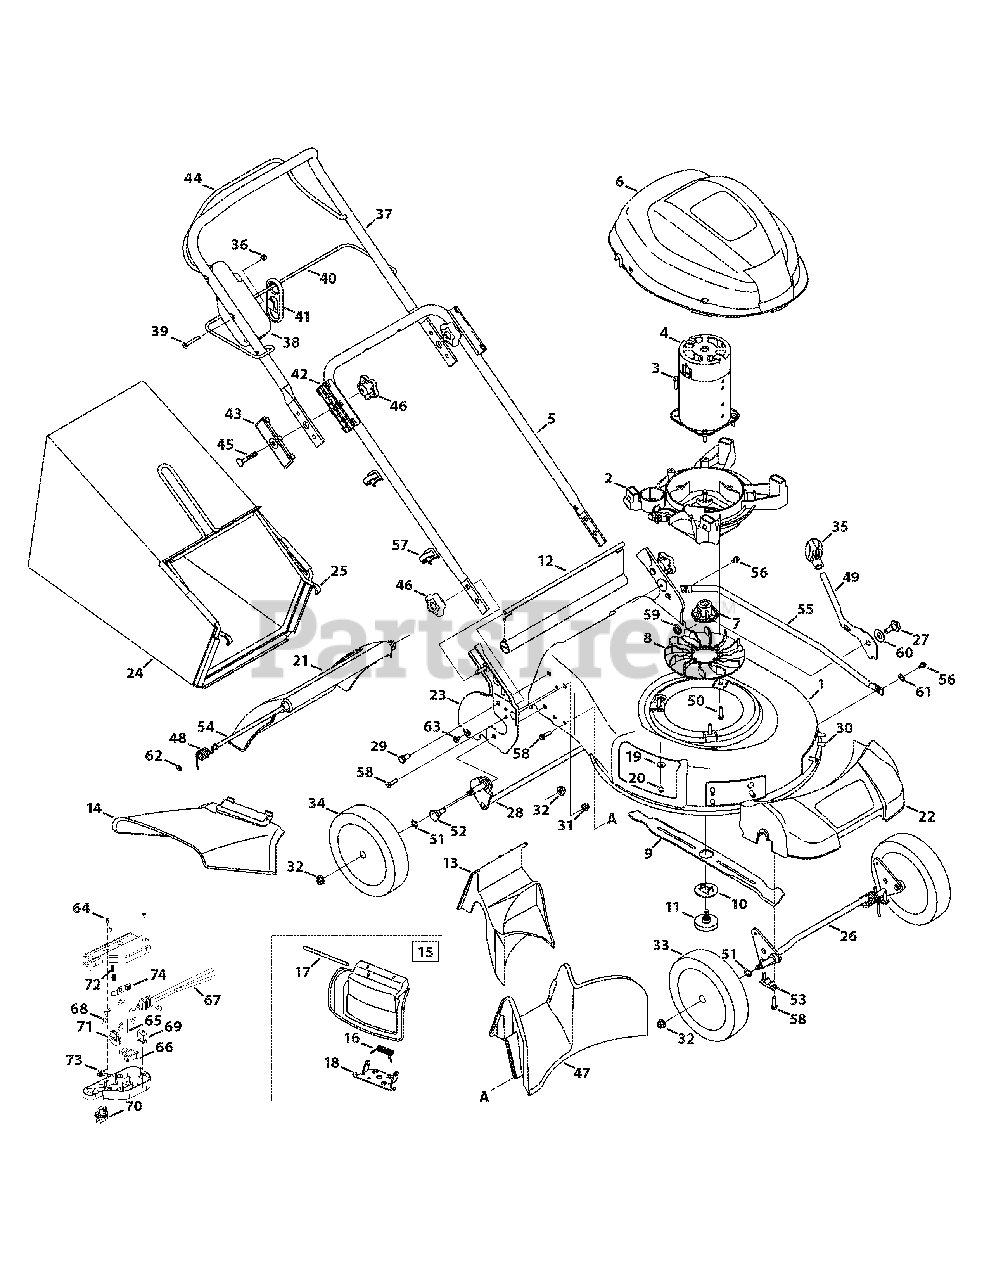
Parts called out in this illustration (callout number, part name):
2	Motor Bracket
3	Screw, 1/4-15 x .750
4	Electric Motor, 120V
6	Motor Shroud
8	Electric Fan
9	Mulching Blade
10	Blade Locking Plate
11	Blade Bolt Assembly
12	Trail Shield
13	Rear Mulch Plug
14	Side Discharge Chute
15	Mulch Plug (Incl. 16-18)
16	Torsion Spring
17	Hinge Pin
18	Chute Deflector Adapter
19	Beleville Washer
22	Front Cover
23	Handle Bracket - RH
23	Handle Bracket - LH
25	Grass Bag Frame
26	Front Bracket Assembly
27	Screw, Shoulder, .50 x .66
28	Rear Bracket Assembly
29	Screw, 5/16-18 x .625
30	Screw, 5/16-14 x .750
31	Nut, Flange Lock, 5/16-18
32	Nut, Flange Lock, 3/8-16
33	Front Wheel
34	Rear Wheel
36	Nut, Hex Lock, 1/4-20
37	Upper Handle
38	Motor/Blade Control
39	Screw, Flat, 1/4-20 x 1.75
41	Cord Retainer
42	Lower Handle Insulator
43	Upper Handle Insulator
44	Motor/Blade Control Handle
45	Bolt Carriage, 5/16-18 x 2.50
47	Rear Baffle
48	Door Torsion Spring - RH
48	Door Torsion Spring - LH
49	Spring Lever
50	Screw, 5/16-12 x .750
51	Washer, Wave, .510 x .750 x .017
52	Screw, Shoulder, .500 Dia. X .434
53	Bushing, Lock, .505 Dia. X .62
54	Rear Door Pivot Rod
55	Cross Bracket
56	Screw, Shldr., 1/4-20 x .50
57	Cable Guide
58	Screw, 1/4-15 x 1.000
59	Spacer, .515 x 1.00 x .310 Lg.
60	Washer, Bell, .510 x 1.14 x .040
61	Washer, Wave, .390 x .825 x .016
62	Nut, Speed
63	Screw, #10-16 x .500
64	Screw, 10-9 x .50
65	Switch Pivot Shaft
67	Wiring Harness
68	Jumper Wire
69	Circuit Breaker
70	Bail Lock Clip
71	Bail Lock Button
72	Compression Spring, .260 x .687
73	Torsion Spring
74	Switchbox Lever
